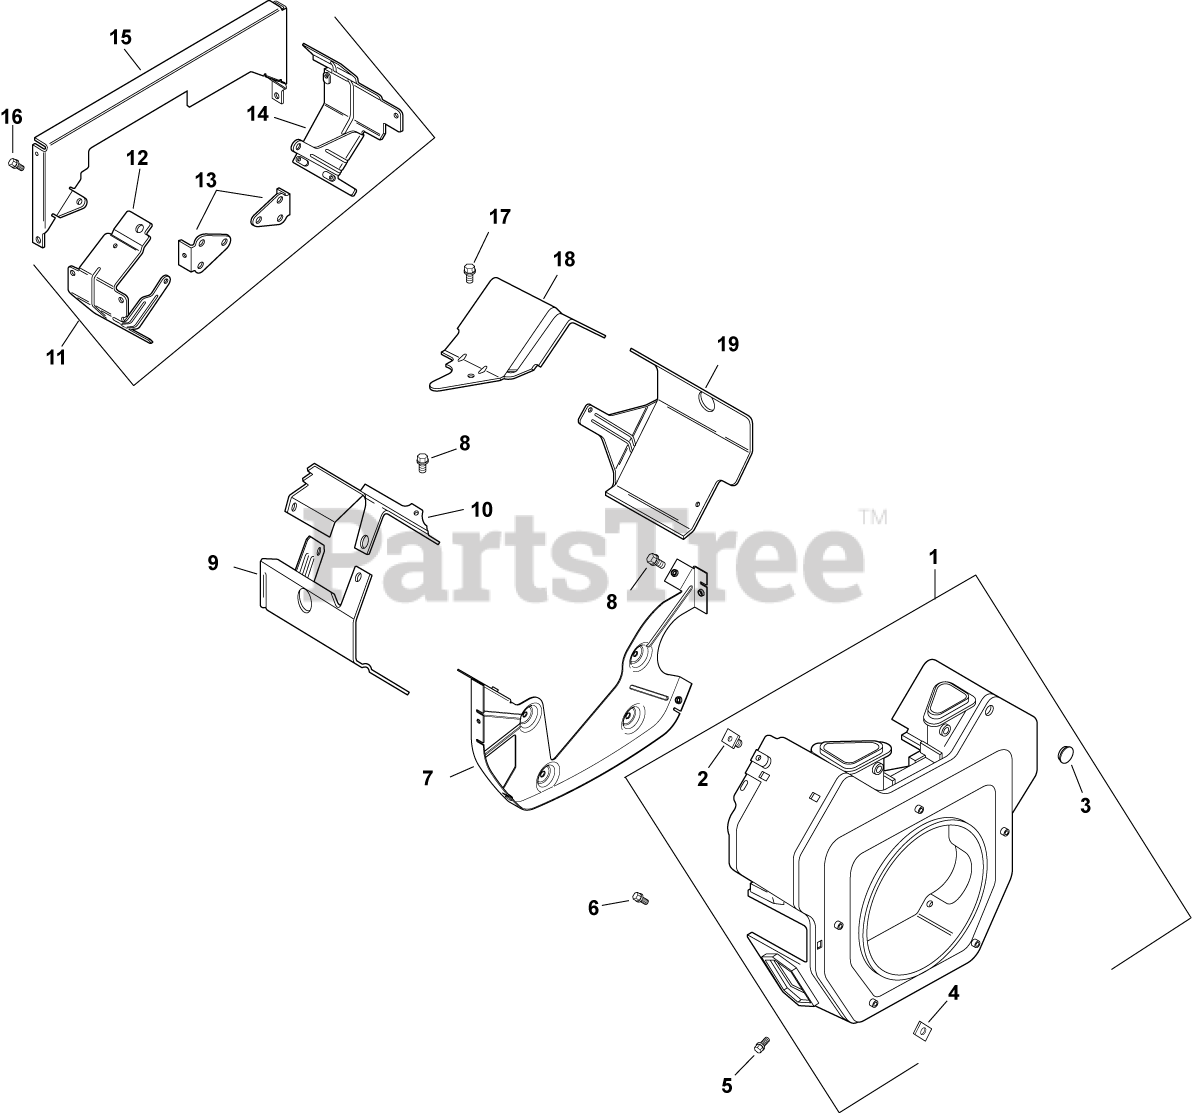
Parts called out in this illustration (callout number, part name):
1	KIT, BLOWER HOUSING ASSY - (#DSC)
1	HOUSING, BLOWER
2	PLUG, BUTTON 9/16
3	NUT, PLASTIC (KM)-USE 25 100 37-S
4	NUT, PLASTIC
5	SCREW - USE M-545016-S
6	SCREW, FLG THD FRM M5X.8X20-(#25086399S)
7	PLATE, BACKING-USE 24 146 59-S
8	SCREW,FLG THD FRM M6X1.0X16-(#25086397S)
9	KIT, CYL BAFFEL #2 SIDE
10	BAFFLE, VALLEY #2 SIDE-USE 24 063 94-S
11	KIT, "Q"DUCT"
12	BAFFLE, DUCTED AIR-OIL FILTER
14	BAFFLE, DUCTED AIR-STARTER
15	PLATE, BACKING
16	SCREW, FLG M6X1.0X10
17	SCREW, FLG THD FRM M5X.8X10
18	BAFFLE, VALLEY (CH)-USE 24 063 93-S
19	KIT, CYL BAFFEL #1 SIDE
2508643-S	SCREW, SKT SET #10-24X1/4"
